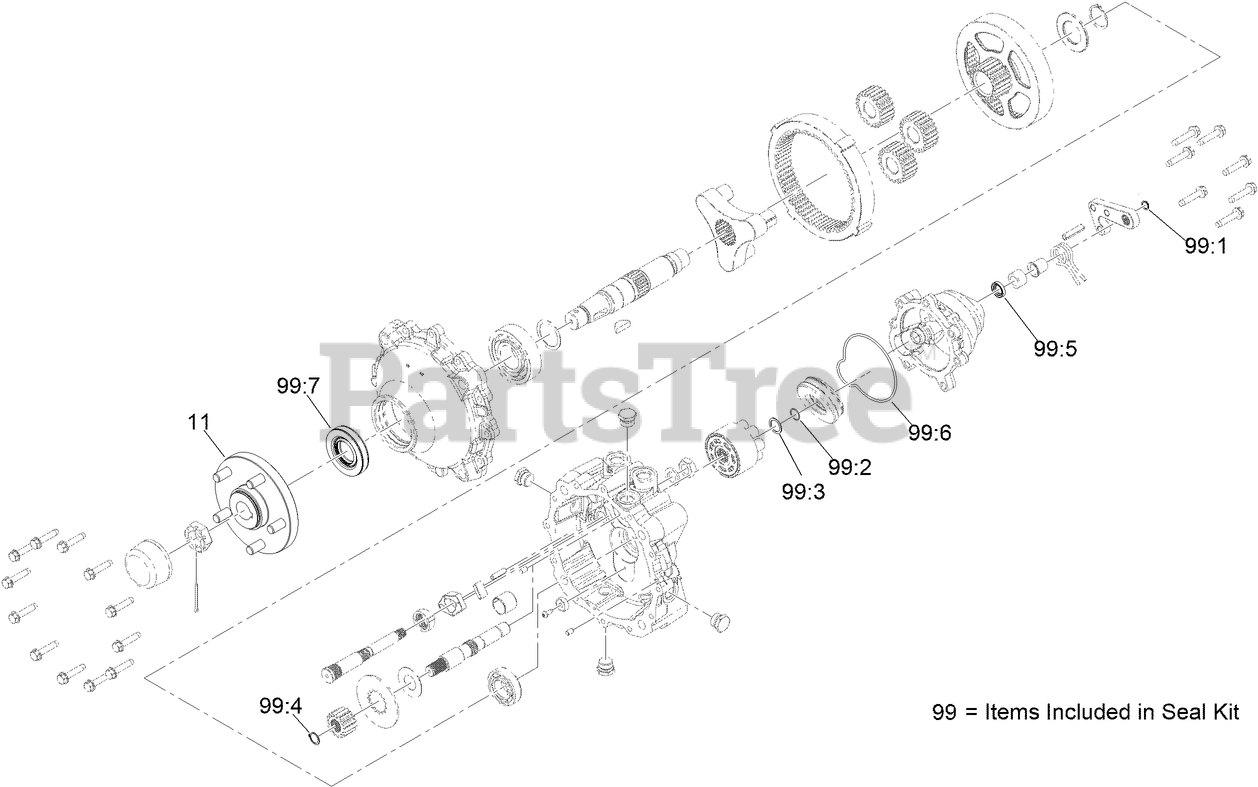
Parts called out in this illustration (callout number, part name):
11	5 STUD WHEEL HUB KIT
99	SEAL KIT
99:1	RETAINER RING
99:2	RING-RETAINING
99:4	RING-RETAINING
99:5	Seal, Brake
99:6	O-Ring, Round
99:7	Seal, Axle
